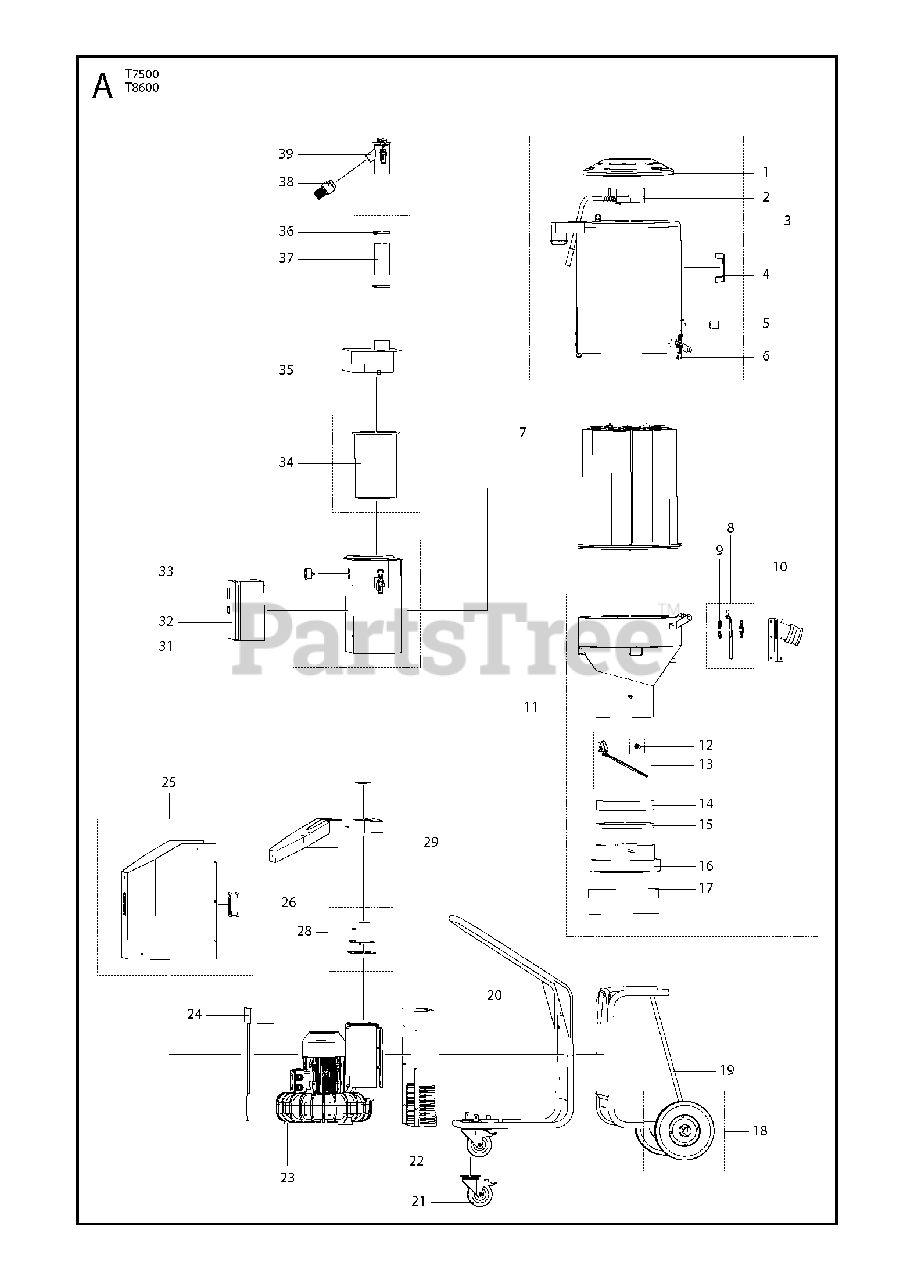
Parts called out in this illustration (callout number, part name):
32	ELECTRONIC BOXT7500 230V 7,5 kW
32	ELECTRONIC BOXT8600 480V 8,6 kW
32	ELECTRONIC BOXT8600 400V
32	ELECTRONIC BOXT7500 400V 5,5 kW
